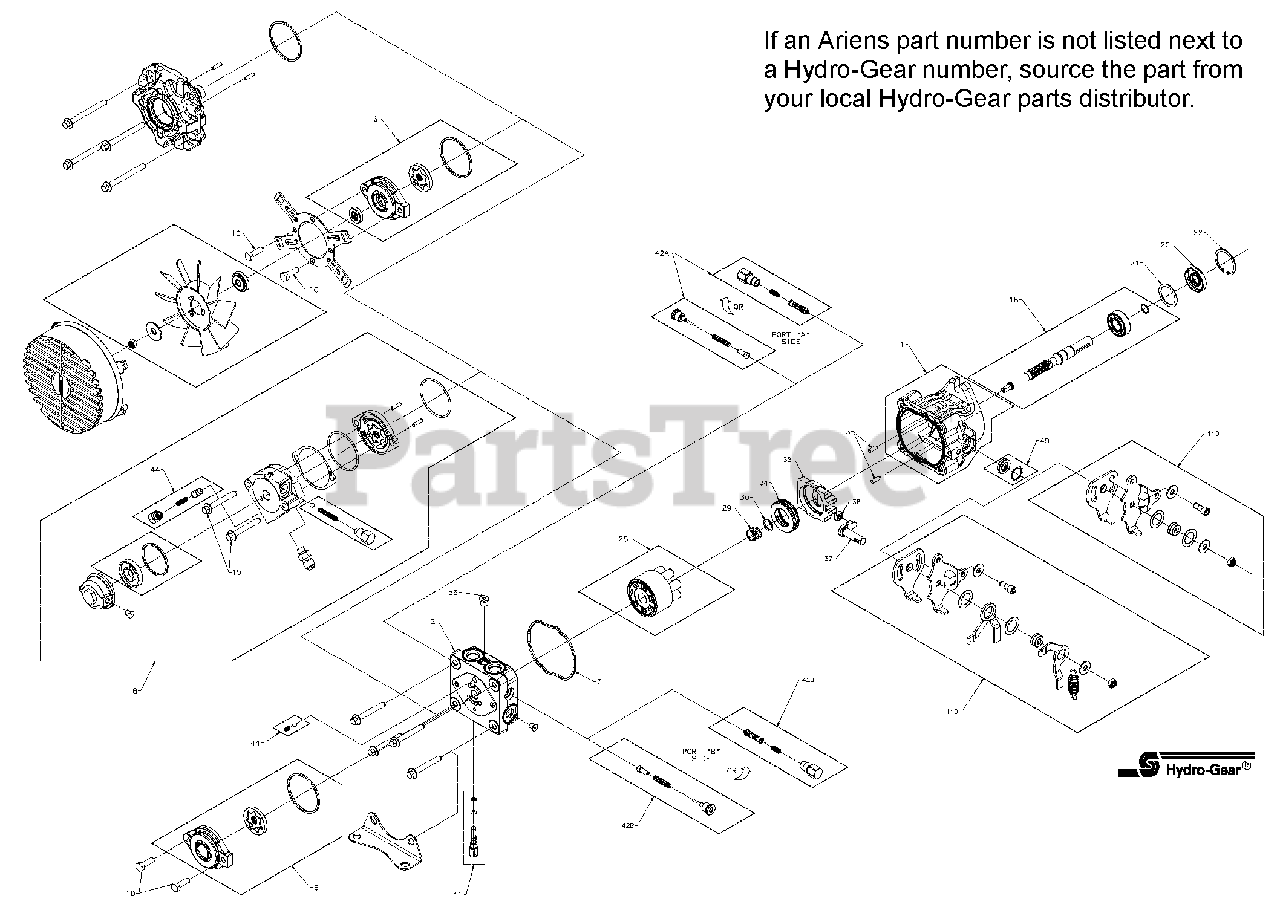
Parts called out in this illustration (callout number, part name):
1	Kit, Housing
2	End Cap
3	Pin, .219 x 1
5	O-Ring, Housing
10	HHCS 5/16-18 x 1
15	Kit, Bypass Valve
18	Kit, Pump Shaft 15mm Key
20	Seal, Lip 17 x 40 x 7
21	Washer 1.23 x 1.56 X .04
22	Ring, Ret 1.56 Int
29	Spring, Block
30	Washer, Thrust .59 x .78 x .04
32	Swashplate 10cc
34	Bearing, Thrust Ball 30 x 52 x 13
37	Arm, Trunnion
38	Guide, Slot
42	Kit, Shock Valve 200 Bar
44	Kit, Charge Relief
49	Kit, BDP-10l Seal
56	Plug 7/16-20 (Metal)
110	Return Kit
NS	Kit, Overhaul Seal
